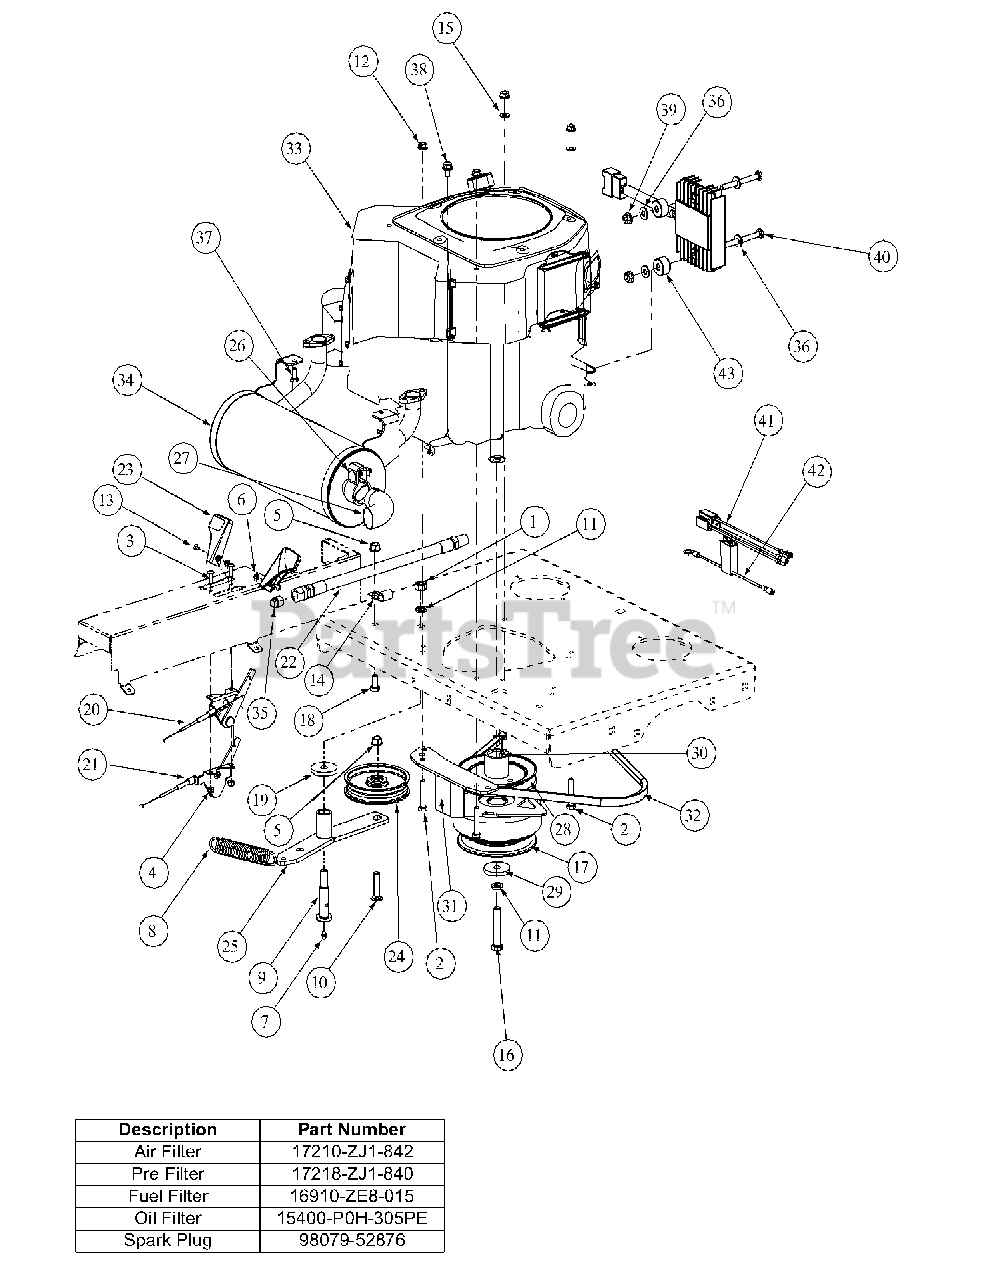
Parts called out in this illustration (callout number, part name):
1	Hex Nut, 7/16-14
2	HHCS, 5/16-18, 1-3/4
3	Round Hd. Machine Screw, 10-32 x 3/4
4	Lock Nut, Nylon Insert, 10-32
5	Flange Lock, Hex Nut, 3/8-16
6	Nut Washer, W/Star, 8-32
7	Grease Fitting, 1/4-28 x 3/16
8	Extension Spring, 1.0 OD x 5.125
9	Shoulder Screw, 7/16-14
10	Hex Carriage Screw, 3/8-16, 1.75
11	Lock Washer, 7/16
12	Hexflange Lock Nut, 5/16-18
13	Machine Screw, 8-32, .375
14	Clip, Heat Shield Cable
15	Flat Washer, 5/16
16	Capscrew, 7/16-20 x 3.50
17	Clutch Electric, Ogura JD08
18	Hex Cap Screw, 3/8-16, .750
19	Flat Washer, 7/16 ID x 1.75 OD x .25
20	Choke Control Cable
21	Throttle Control Cable
22	Oil Drain Hose
23	Control Throttle Knob
24	Flat Pulley with Flanges
25	Engine Idler Arm Assembly
25	Bearing
25	Engine Idler Arm Assembly Cast
26	Tube Clamp, 1.50
27	Muffler Accessory Exhaust Tube
27	Muffler Accessory, Straight Exhaust Pipe
27	Screw, 8-32 x 0.375
28	Trans Drive Pulley
29	Flat Washer, 7/16 ID x 1.75 OD x .25
30	Key, 1/4 x 1/4 x 2.75
31	Retainer Clutch Assembly, Ogura
32	Belt, 51.2 Lg
33	Engine, 20HP Honda
34	Muffler
35	Pipe Plug, 3/8 NPT
36	Flat Washer, 1/4
37	Hex Cap Screw, M8-1.25 x 18mm
38	Screw, M6 x 1.0 x 12mm
39	Nut, 1/4-20, Hex Flange Lock
40	Hex Cap Screw, 1/4-20 x 2.50
41	Wire Harness Adapter
42	Charge Regulator Wire
43	Spacer, .281 ID x .875 OD
